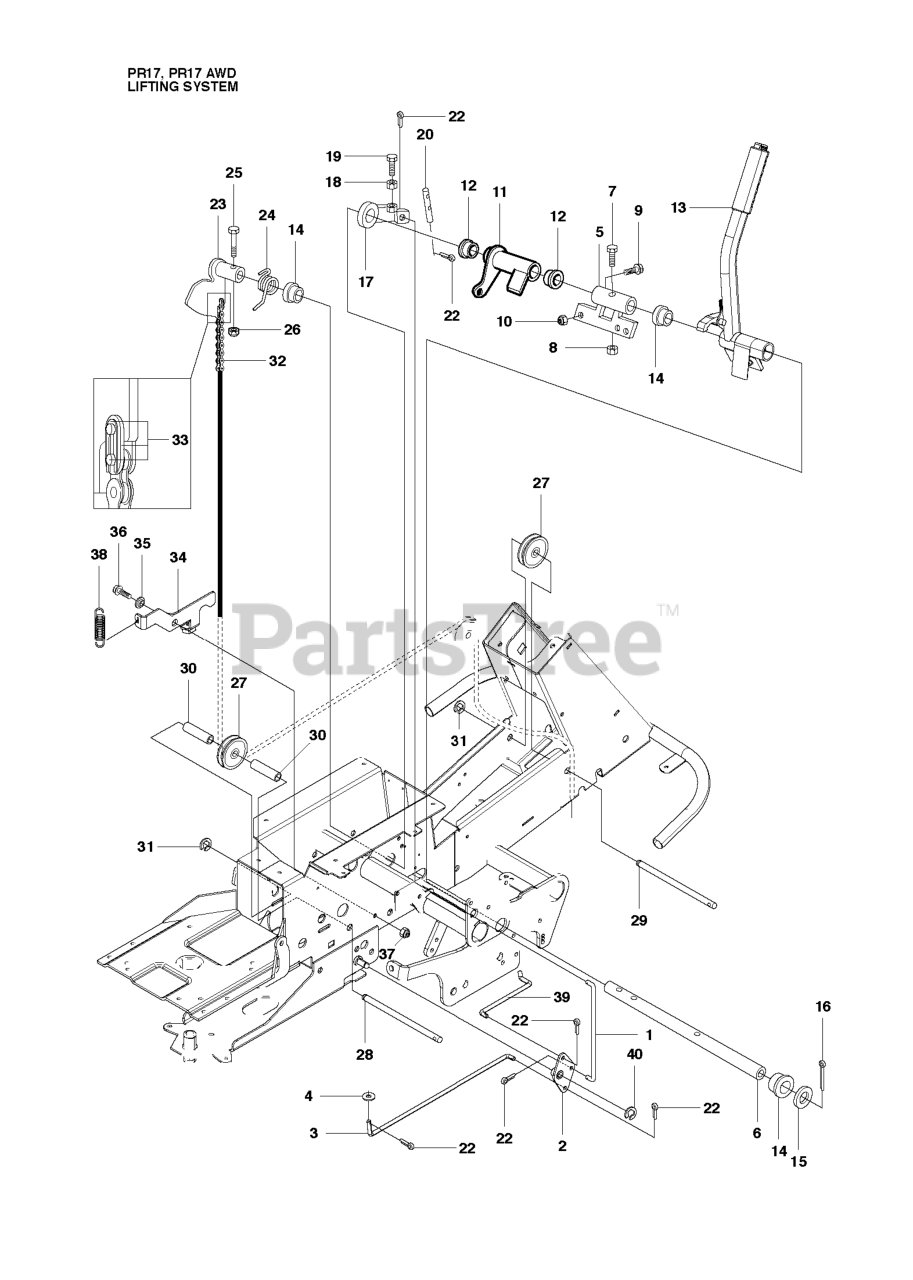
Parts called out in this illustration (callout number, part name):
9	SCREW M6S 8X25
10	NUT
12	BEARING FLANGE
13	LIFTING LEVER ASSY
14	BEARING FLANGE
17	LEVER CLUTCH
18	NUT
35	WASHER
36	BOLT
37	LOCKNUT M8
40	RETAINING RING
